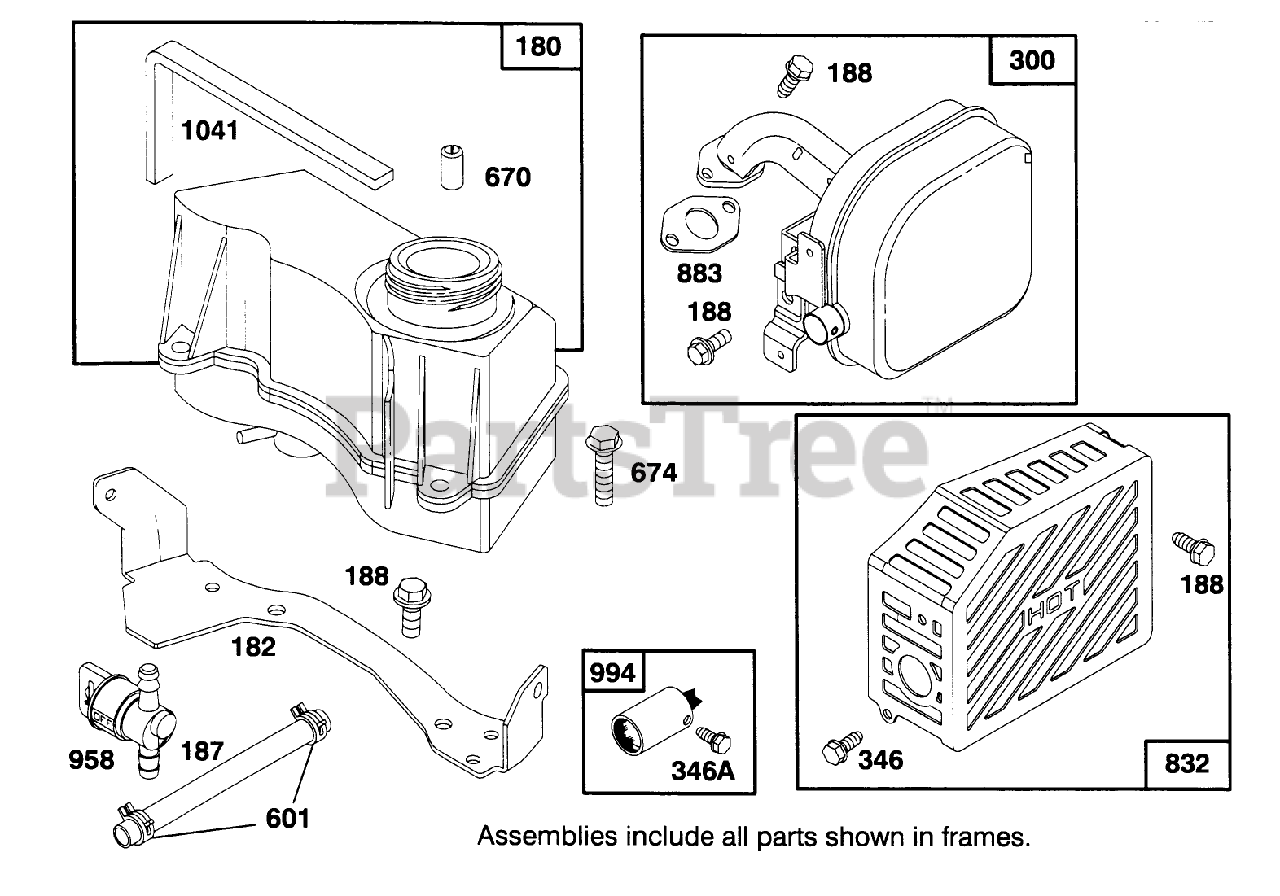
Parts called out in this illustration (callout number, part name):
180	TANK ASSY - FUEL
300	MUFFLER - EXHAUST
601	CLAMP - CL PIPE
670	SPACER
674	SCREW - HEX HEAD
